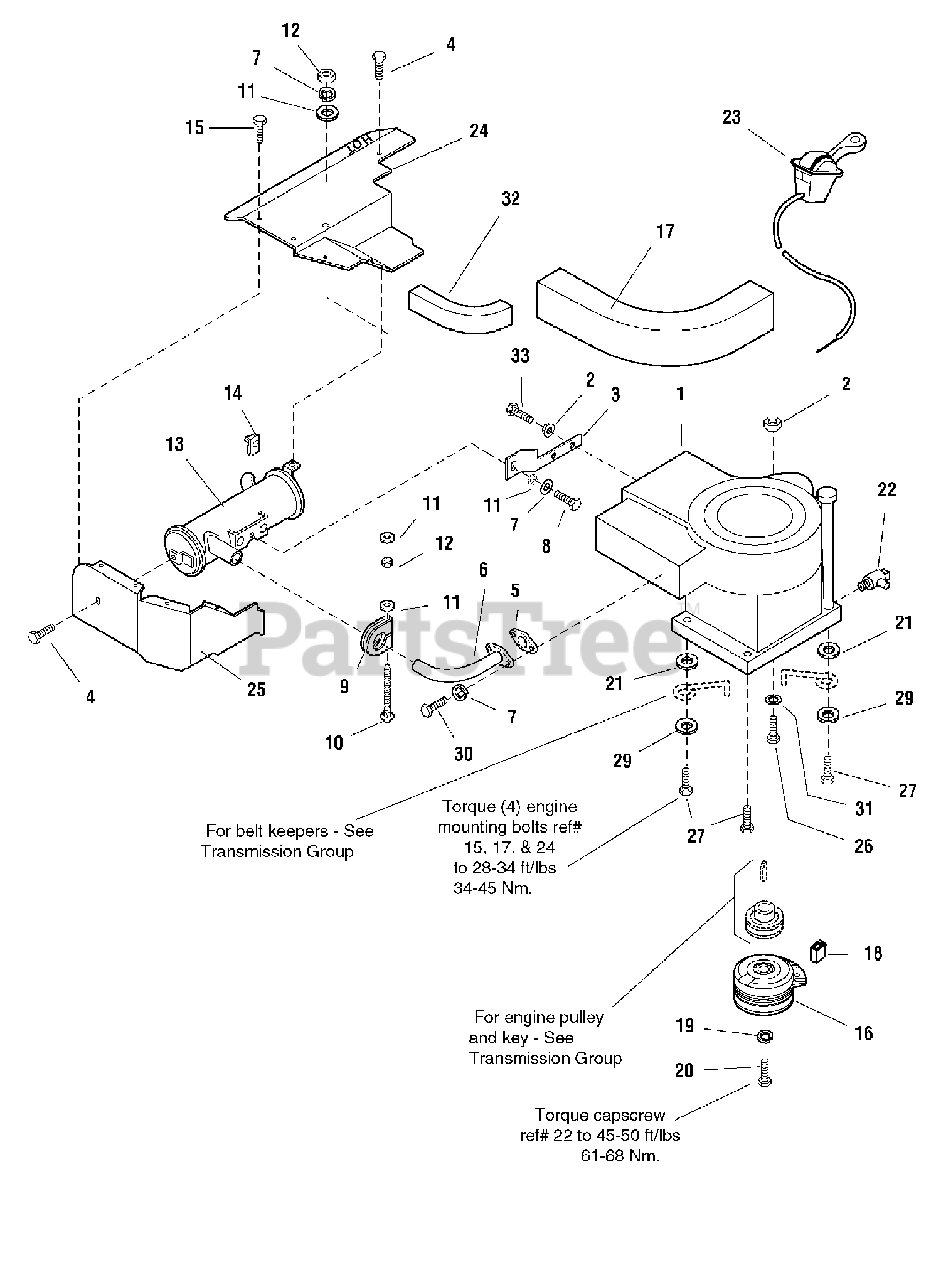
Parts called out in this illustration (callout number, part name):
1	* ENGINE, 14.5 HP B&S INTEK, Model 31E577-0116-G5
2	NUT, 5/16-18, Serrated Lock Flange, GR5
3	SUPPORT, Muffler
4	CAPSCREW, Taptite, 5/16-18 x 1/2
5	GASKET, Muffler
6	PIPE, Exhaust, 1.125 OD, 4 Bends
7	LOCKWASHER, 5/16, Split
8	CAPSCREW, 5/16-18 x 1
9	CLAMP, Muffler, 1.312 Dia.
10	BOLT, Carriage, 5/16-18 x 3-1/4
11	WASHER, 5/16, Flat
12	NUT, Hex, 5/16-18
13	MUFFLER ASSEMBLY
14	NUT, Speed, 5/16-18
15	SCREW, #10-16 x 1/2
16	CLUTCH, Electric (15217-2)
17	SEAL, Air Inlet, 17.8 Lg
18	SLEEVE, Clutch Anchor
19	LOCKWASHER, 7/16
20	CAPSCREW, 7/16-20 x 2-12
21	WASHER, Flat, 7/16
22	VALVE, Shut Off
23	THROTTLE CONTROL, 37 Lg, W/Knob
25	DUCT, Bottom
26	CAPSCREW, Hex, Whiz, 5/16-18 x 1-1/2
27	CAPSCREW, Taptite, 3/8-16 x 1-1/2
29	WASHER, 3/8
30	CAPSCREW, Socket Head, 5/16-18 x 3/4
31	PUSHNUT, 5/16
32	EDGING, Seal, 13.9 Lg
33	CAPSCREW, Taptite, 1/4-20 x 7/8
